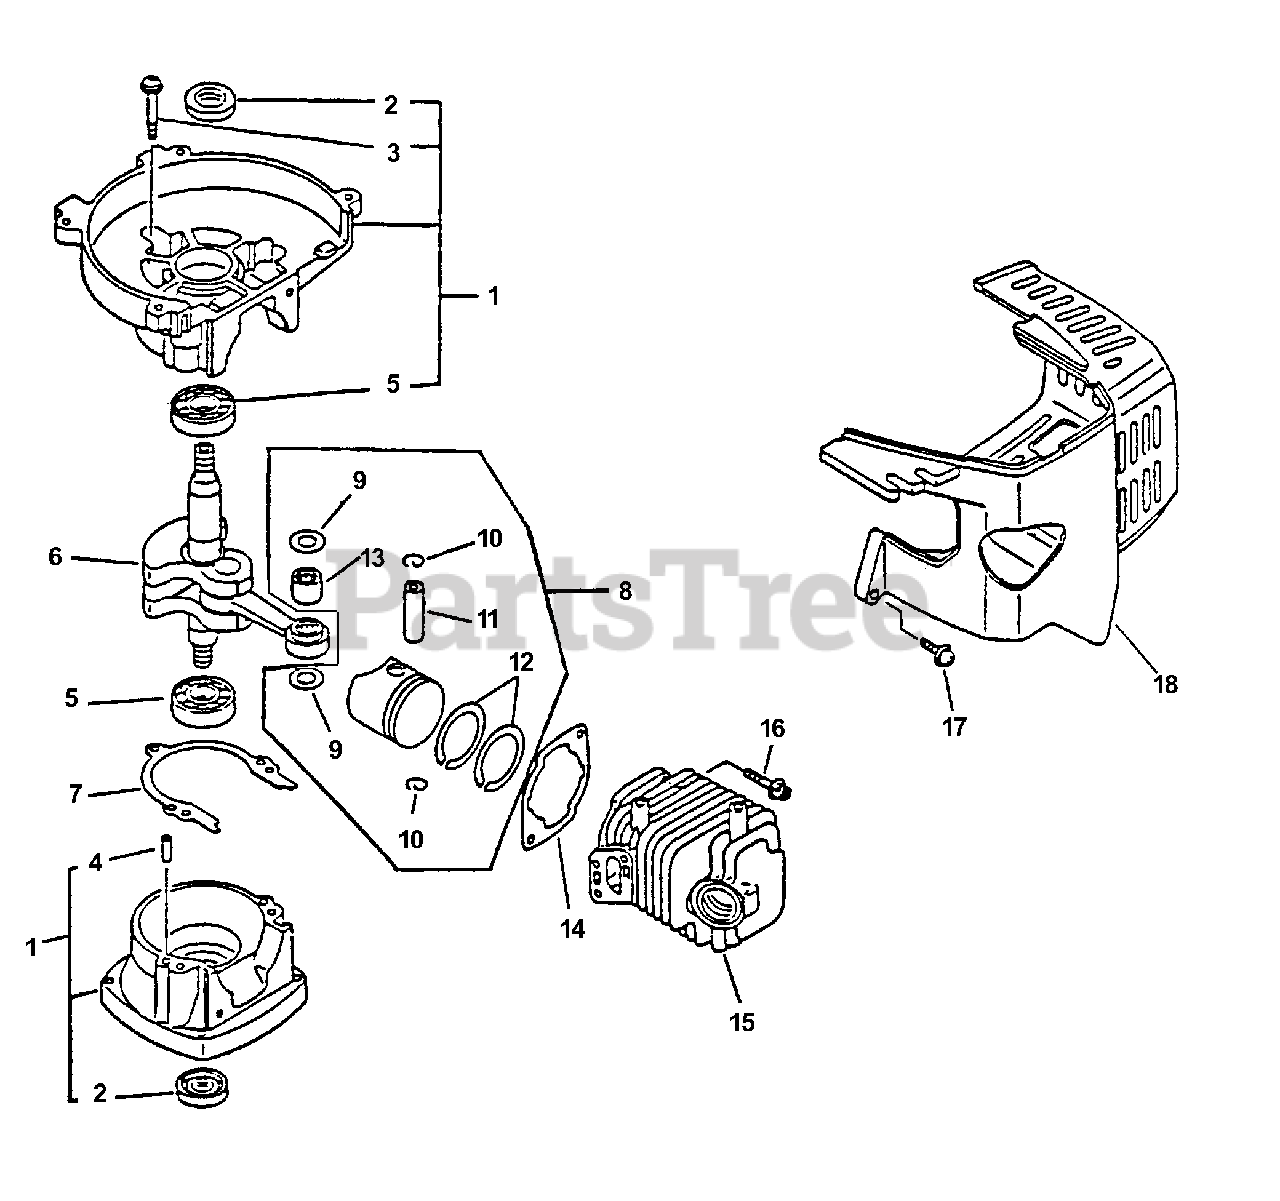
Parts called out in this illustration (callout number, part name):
1	CRANKCASE KIT
2	SEAL, OIL
3	SCREW - 5X28
4	PIN - LOCATING
5	BEARING, BALL - 6201
6	CRANKSHAFT ASSY
7	GASKET, CRANKCASE
8	PISTON KIT
10	RING, RETAINING
11	PIN, PISTON
12	RING, PISTON
13	BEARING, NEEDLE - 8
14	GASKET, CYLINDER
15	CYLINDER
16	SCREW - 5X22
17	SCREW - 4X22
18	COVER, ENGINE
